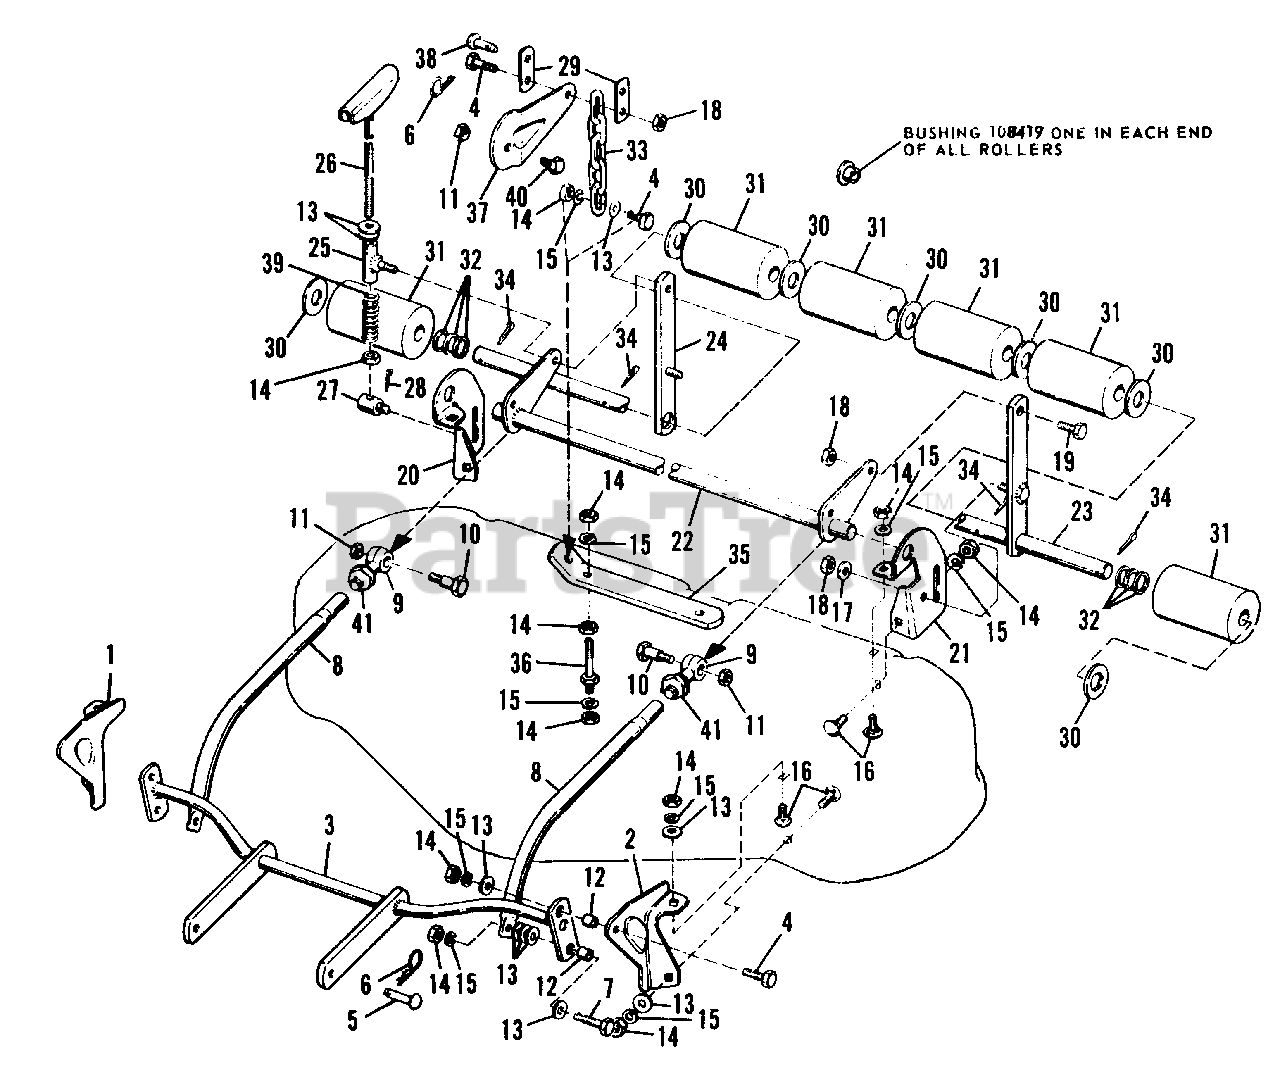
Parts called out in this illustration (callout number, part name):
1	BRACKET, Front, R.H.
2	BRACKET, Front, L.H.
3	MOWER HITCH ASSY.
4	CAPSCREW, Hex, 3/8-16 x 1
6	CLIP, Spring
7	CAPSCREW, Hex, 3/8-16 x 1-1/4
8	ARM, Adjusting
10	BOLT, Shoulder
11	LOCKNUT, Hex, Full, 3/8-16
13	WASHER, Plain, 3/8
14	NUT, Hex, Jam, 3/8-16
15	LOCKWASHER, 3/8
16	BOLT, Carriage, 3/8-16 x 3/4
17	WASHER, Plain, 5/16
18	LOCKNUT, Hex, Full, 3/8-16
19	CAPSCREW, Hex, 3/8-16 x 7/8
20	BRACKET, Roller, R.H.
21	BRACKET, Roller, L.H.
22	LEVER ASSY., Rear
23	BAR & SHAFT ASSY.
24	ROLLER BAR ASSY.
25	SOCKET ASSY., Crank
26	ADJUSTMENT SCREW ASSY.
28	PIN, Cotter, 3/32 x 3/4
29	MOWER LIFT LINK
31	ROLLER W/Bushing
32	WASHER (as required)
33	CHAIN
34	PIN, Cotter, 3/16 x 1
35	BAR, Lift
37	LEVER, Lift, Mower
38	PIN, 3/8 x 1
40	CAPSCREW, Hex, 3/8-16 x 7/8
41	NUT, Hex, Jam, 1/2-20
